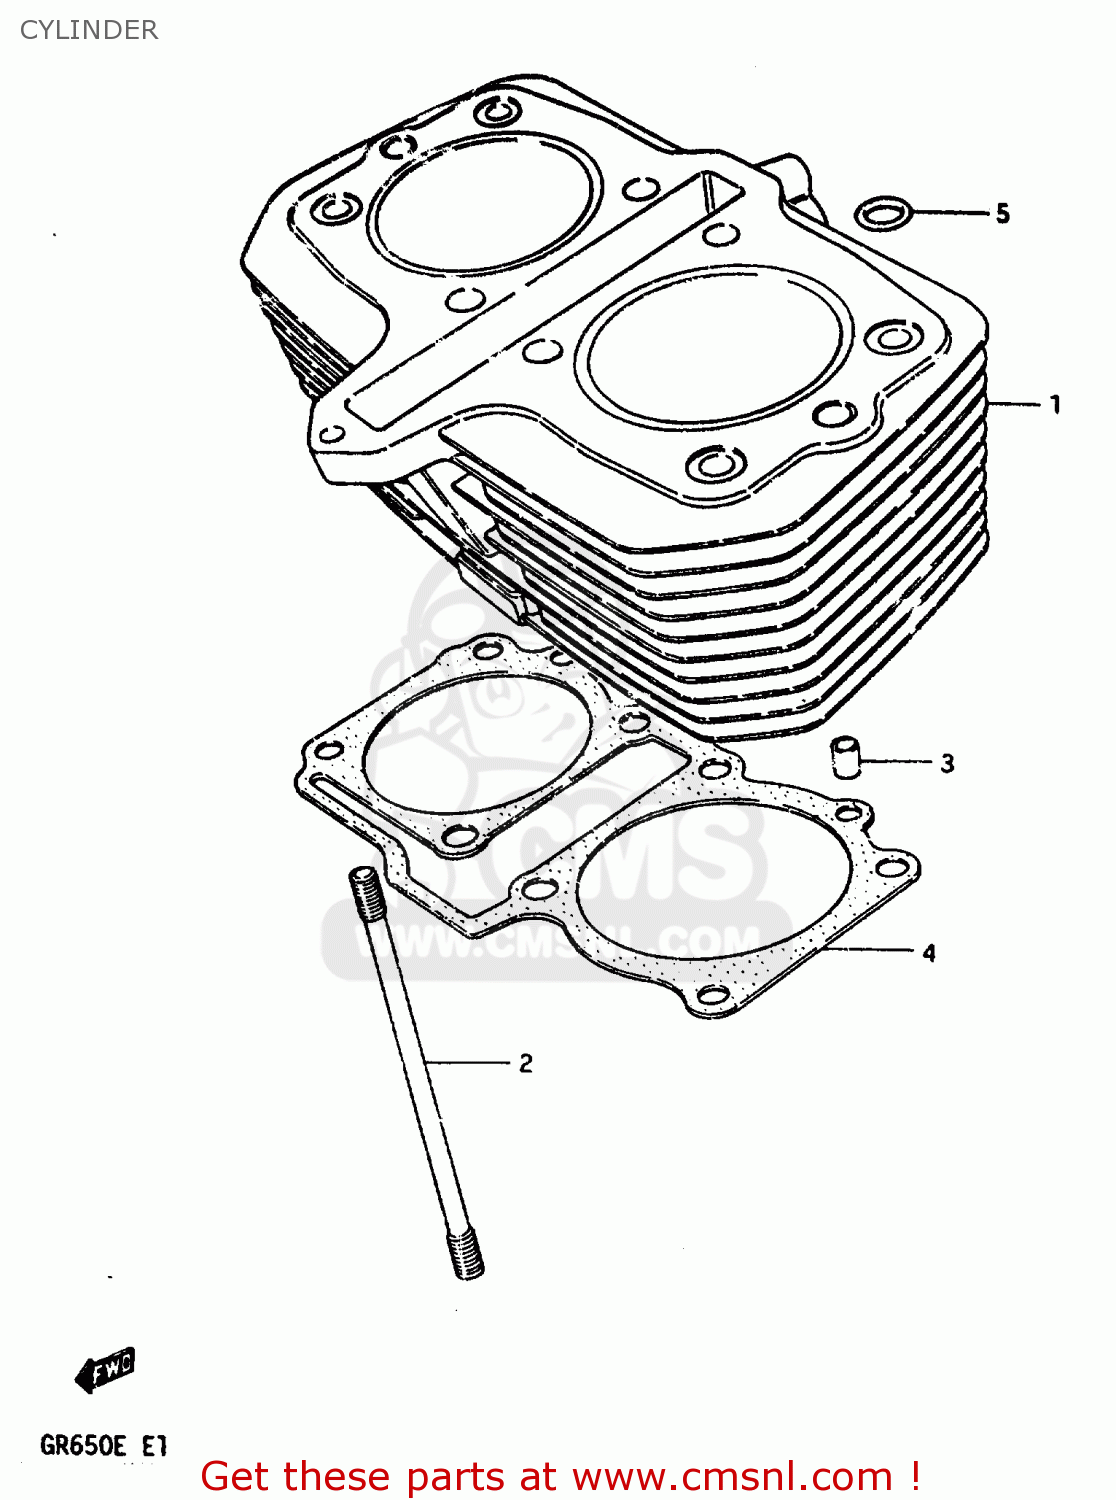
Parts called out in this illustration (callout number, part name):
1	CYLINDER
2	STUD
3	PIN
4	GASKET,CYLINDER (MCA)
5	O RING(D:2.4,ID:11)
